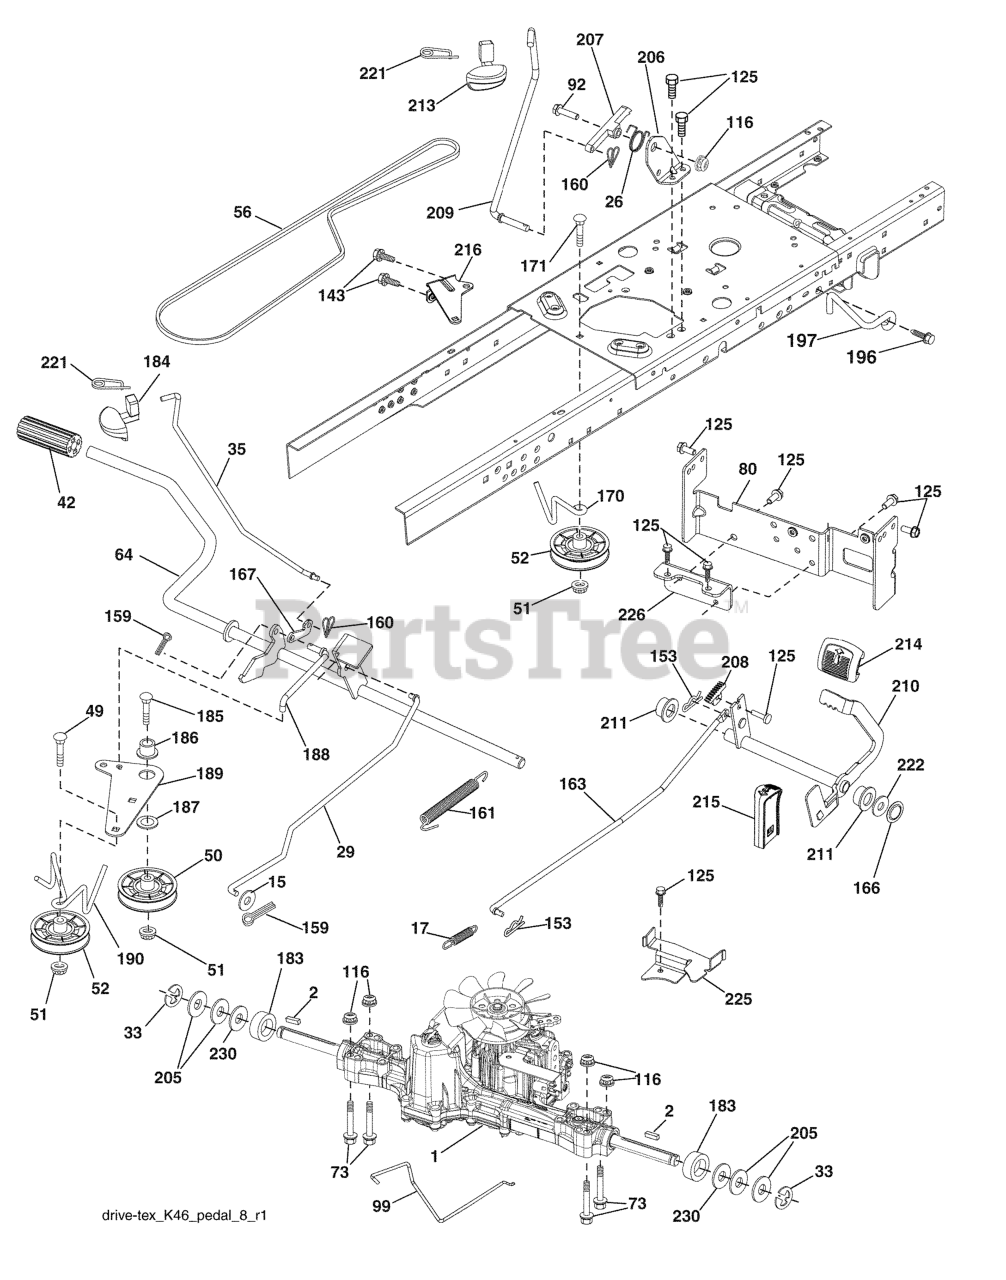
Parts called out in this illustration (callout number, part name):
1	TRANSAXLE, TUFFTORQ K46
2	SQUARE KEY
15	WASHER
17	SPRING.BRAKE.K46.GREEN
26	SPRING.RETURN.CRUISE
29	ROD.BRAKE.K46
35	ROD.BRAKE.PARKING.GT.H
42	PEDAL COVER T
50	IDLER.FLAT.910.OFFSET
51	NUT LOCK FLG 3/8-16 UNC
52	IDLER.V-GROOVE.910.OFFSET
56	V-BELT.MOWER.92.40.42/K46
64	SHAFT.ASM.PEDAL.BRK.CNTR
73	BOLT HEX 5/16-18 GR 5
80	STRAP TORQUE
92	BOLT
99	ROD.SPRING.BYPASS.K46.LT.Z
116	NUT LOCK HEX FLANGE 5/16-18
125	SCREW
143	Screw 5/16-18 x 1/2
153	RETAINER M
159	COTTER PIN
160	RETAINER CLIP
161	SPRING, RETURN LT
163	ROD.CONTROL.PEDAL.K46
166	NUT.PUSH.625.2006
167	LATCH.BRAKE.SPRING
170	KEEPER.V-IDLER.CENTER.
171	BOLT
183	SPACER AXLE
184	HANDLE.PARKG.BRK.HUSQ X667
186	SPACER.RETAINER
187	WASHER 12/32X2X10GA
188	RP.LINK.CLUTCH.GROUND.DRIVE
189	BELLCRANK.GROUND.DRIVE.TEX.
190	KEEPER.BELLCRANK.DRIVE
196	SCREW 3/8-16X1
197	LINK.CLUTCH.ANIT-ROTAT
206	BRKT.MOUNT.LATCH.CRUIS
207	LATCH.CONTROL.CRUISE
208	GEAR.SECTOR.CONTROL.CR
209	ROD.CONTROL.CRUISE.GT.
210	ROCKER.ASM.PEDAL.CONTR
211	BEARING.NYLON
213	KNOB.CONTROL.CRUSIE.HU
214	PEDAL.FORWARD.HUSQVARNA.DEALER
215	PEDAL.REVERSE.TEX.GT.4
216	BRACKET.PULLEY.IDLER.W/TEX
221	RETAINER.SPRING.CLIP.H
222	WASHER 21/32 X 1-1/4 X 10 GA.
225	KEEPER.BELT.TRANSAXLE.K46
226	BRACKET.MOUNT.TORQUE.K46.TLT
230	WASHER.HARDENED
